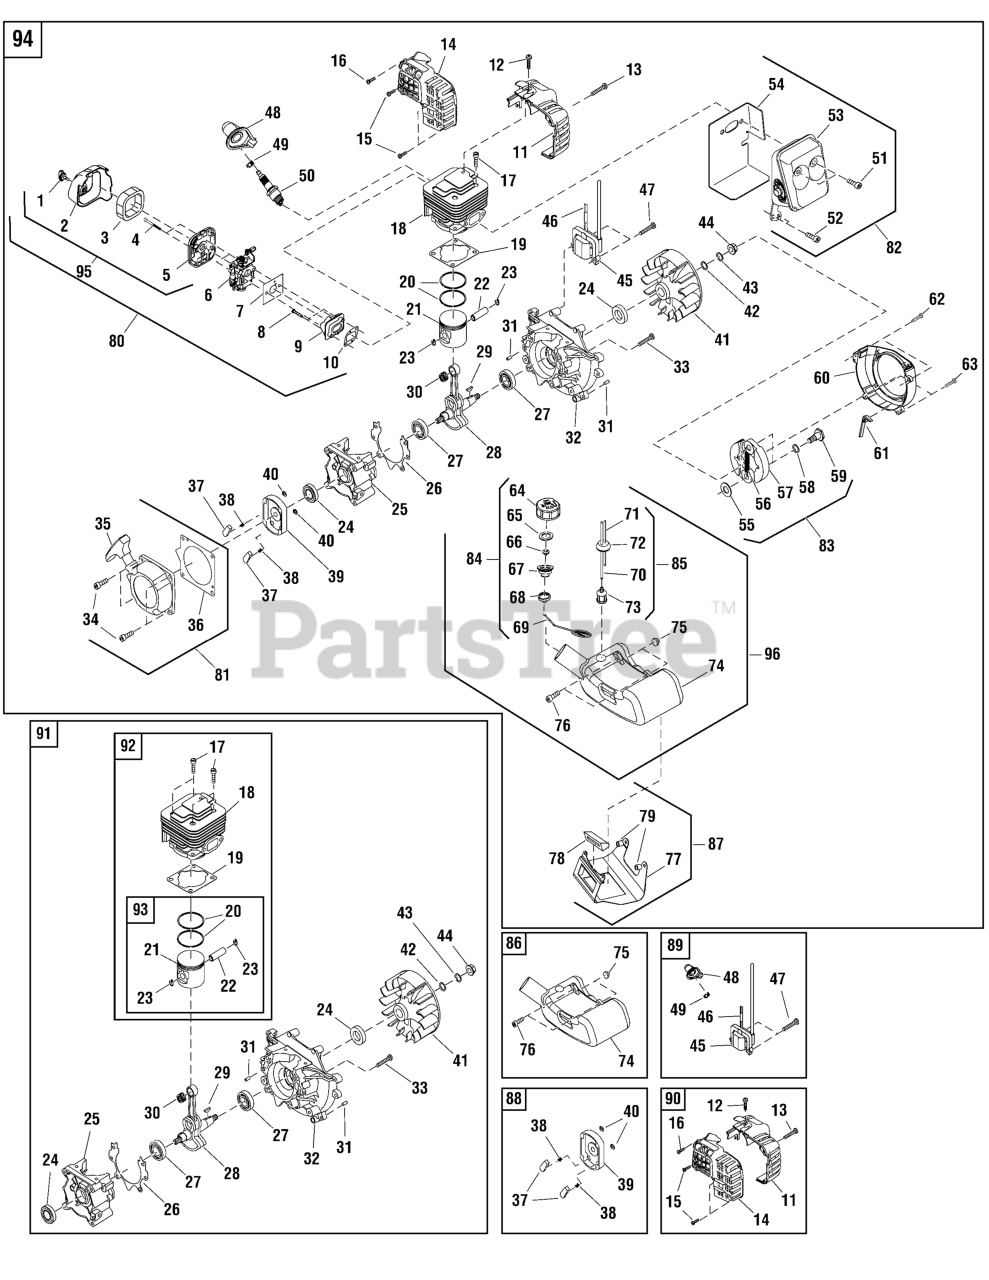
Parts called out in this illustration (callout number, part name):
2	COVER, Cleaner, Outer
3	FILTER
5	COVER, Cleaner, Inner
6	CARBURETOR
7	GASKET, Carburetor
9	ADMITTING PIPE
10	GASKET, Admitting Pipe
11	SHROUD, Front
14	SHROUD, Rear
15	SCREW, Self Tapping, 5×20
16	SCREW, Self Tapping, 4.2 × 30
17	BOLT, M5 x 18
18	CYLINDER
19	GASKET, Cylinder
20	RING, Piston
21	PISTON
22	PIN, Piston
23	PIN RETAIN RING
24	OIL SEAL, 11.7 × 22 × 7
25	CRANK CASE, Rear
26	GASKET, Crank Case
27	BEARING, 6201/P6
28	CRANK SHAFT ASSEMBLY
29	KEY, 3 × 5 × 13
30	NEEDLE BEARING
31	PIN, Cylindrical, B4 × 10
32	CRANK CASE, Front
35	STARTER
36	PAD, Starter
37	STARTER CLINCH
38	SPRING, Starter
39	STARTER BOX
41	FLY WHEEL
42	WASHER, Flat, 8
43	WASHER, Spring, 8
44	NUT, M8
45	MAGNETO COIL
46	CORD, Complete
48	BOOT, Spark Plug
49	CLIP, Spark Plug
50	SPARK PLUG
53	MUFFLER
54	GASKET, Muffler
55	WASHER, B
56	SPRING, Clutch
57	EXPANDER, Complete
58	WASHER, Wave
59	SCREW SHAFT
60	COVER, Fan
61	FLASH PAN
64	LID, Fuel Tank
65	GASKET
66	INLET
67	LID, Inner, Fuel Tank
68	COVER, End
69	CHAIN
70	PIPE, Fuel
71	PIPE, Soft PVC
72	PLUG, Fuel Line
73	FILTER, Fuel
74	FUEL TANK
75	PLUG, Rubber
77	BRACKET, Tank
78	COVER, Rubber
79	PAD, Bracket
80	KIT, Air Cleaner & Carburetor
81	KIT, Starter Assembly
82	KIT, Muffler Assembly
83	KIT, Expander Assembly
84	LID, Fuel Tank, Complete
85	KIT, Fuel Line Assembly
86	KIT, Fuel Tank Assembly
87	KIT, Tank Bracket Assembly
88	START REEL, Complete
89	KIT, Magneto Assembly
90	KIT, Shroud Assembly
91	KIT, Cylinder Assembly
92	KIT, Cylinder Head Group
93	KIT, Piston
94	ENGINE ASSEMBLY, Complete
95	KIT, Air Cleaner
96	KIT, Fuel Tank & Cap
